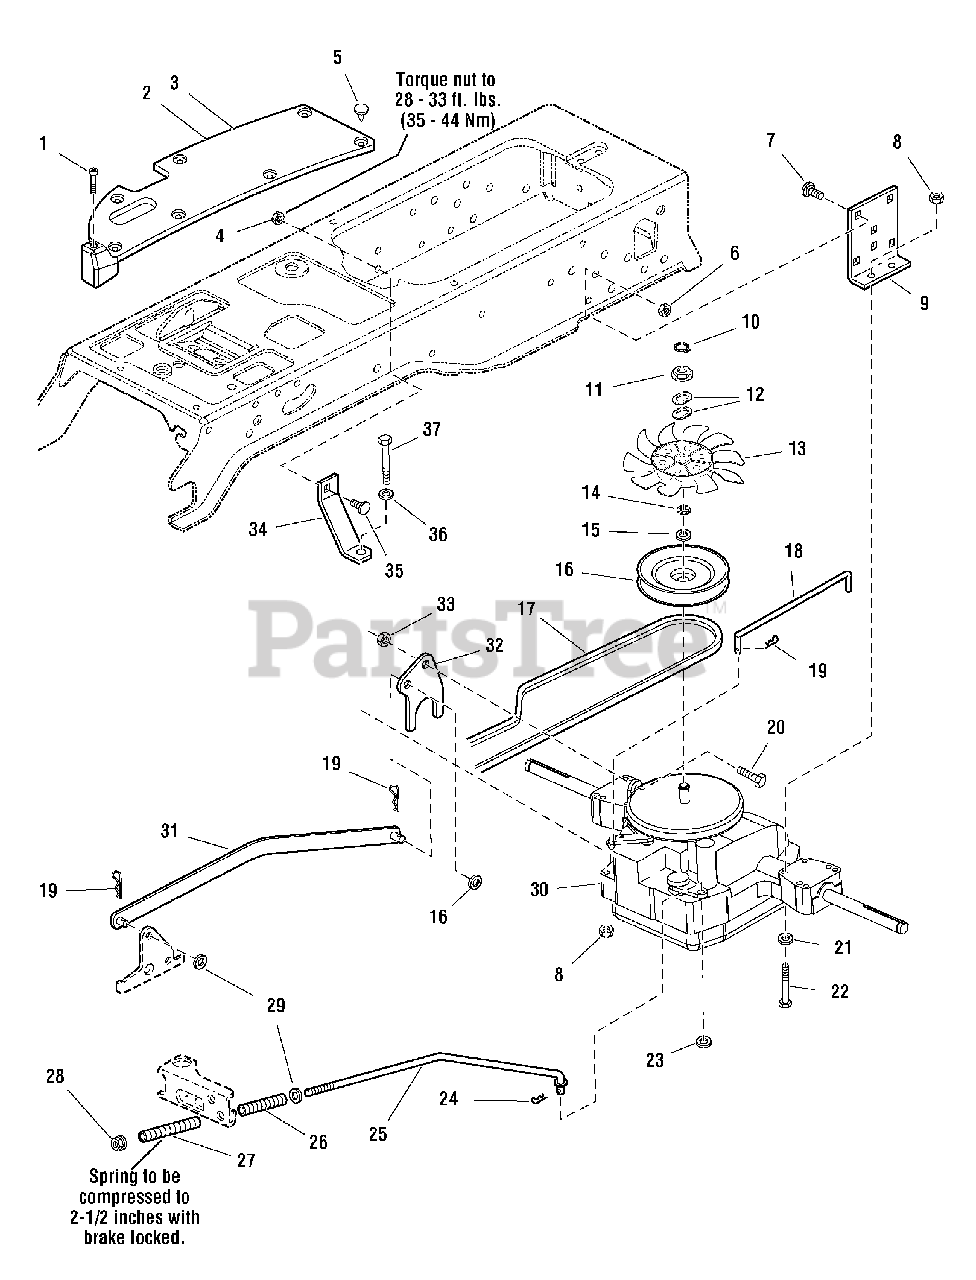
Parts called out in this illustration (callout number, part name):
1	SCREW, Pan Head Torx Taptite, 1/4-20 x 1-1/4, Black
2	PAD, Footrest, LH, without Differential Lock
3	PAD, Footrest, RH
4	NUT, Hex KEPS, 5/16-18, Black
5	FASTENER, Panel
6	NUT, Hex KEPS, 3/8-16, Black
7	CARRIAGE BOLT, 3/8-16 x 1, Black
8	NUT, Hex Flange ESNA, 5/16-18, Black
9	SUPPORT, Transmission
10	RING, Snap, Transmission
11	COLLOR, Spline, Transmission
12	LOCK WASHER, Transmission
13	FAN, 10 Blade, Transmission
14	RING, E, Transmission
15	WASHER, 1/2
16	PULLEY & HUB ASSEMBLY
17	V-BELT, Drive
18	ROD
19	PIN, Quick
21	WASHER, 5/16, Black
22	CAPSCREW, Hex Head, 5/16-18 x 2-3/4, Black
23	WASHER, 15/32 x 15/16, Black
24	PIN, Cotter, Black
26	SPRING, Compression, 3-1/4" Long, Black
27	SPRING, Compression, 3-5/8" Long, Black
28	NUT, Hex FlangeESNA, 3/8-16, Black
29	WASHER, 3/8, Black
0030	ROD, Return
30	TRANSMISSION ASSEMBLY, K57, without Pulley
31	CONTROL ARM ASSEMBLY
32	ARM, Control
33	NUT, KEPS Lock, 5/16-18
34	STRAP, Torque
35	BOLT, Carriage, Short Neck, 5/16-18 x 1
36	WASHER, 5/16, Black
37	CAPSCREW, Hex Head, 5/16-18 x 1-3/4, Balck
0070	SPACER, w/Flange, 11/32 x 15/32 x 3/4
